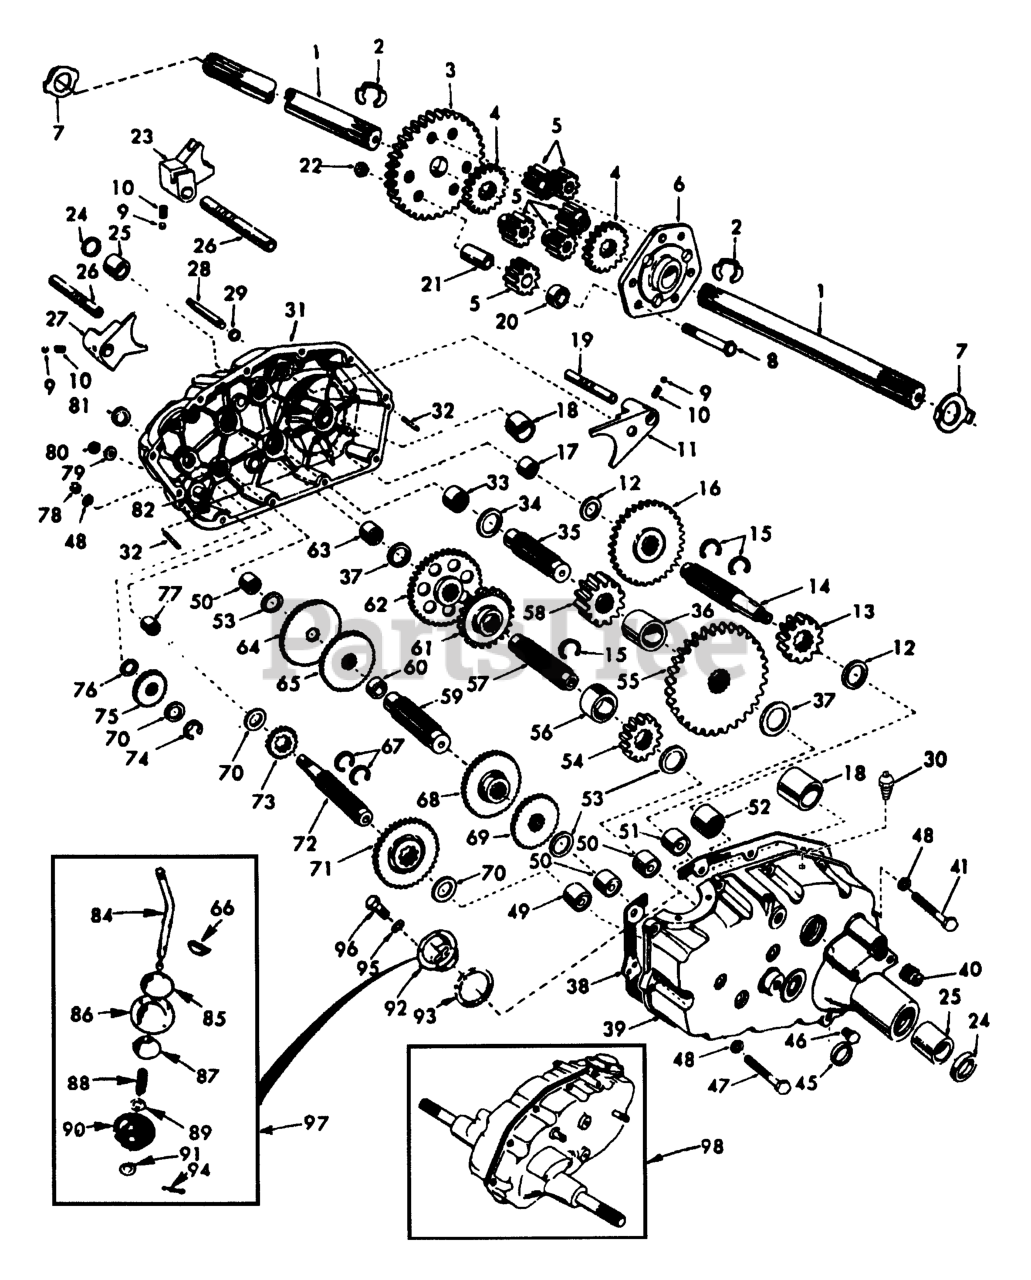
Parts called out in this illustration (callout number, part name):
1	AXLE SHAFT T
2	Retaining Ring
3	FINAL GEAR T
4	DIFF GEAR T
5	DIFF PINION T
6	DIFF CARRIER T
7	WASHER T
8	Bolt, Hex Head 3/8-24 x 3-1/4 (1" Thread Length)
9	STEEL BALL KIT
10	SPRING
12	THRUST WASHER
13	RED PINION T
14	GEAR SHAFT T
15	SNAP RING T
16	GEAR T
18	BEARING
21	PINION RS
22	GRIPCO NUT
24	OIL SEAL STD
25	BRNG. T
26	SHAFT T
27	SHIFT FORK T
28	SHIFT SHAFT
29	SEAL.OIL.SHAFT.SHIFT.T
31	TRANSAXLE 6SP GT
33	NEEDLE BRNG T
34	WASHER RACE BEARING THRUST
35	GEAR SHAFT T
36	GEAR SPACER T
39	Gearcase and Bearings, L.H.
40	Pipe Plug 1/2-14 N.P.T.
41	Bolt, Hex 5/16-18 UNC x 1-5/8
47	HEX BOLT
48	WASHER.LOCK.HVY.HLCL.SPR.5/16
49	BEARING TI
50	NEEDLE BRNG T
51	NEEDLE BRNG T
52	BEARING STD
53	BRNG RACE T
54	RED PINION T
55	RED GEAR T
56	PINION SPACER T
57	GEAR SHAFT T
58	FINAL PINION T
59	GEAR SHAFT T
61	RED PINION T
62	RED GEAR T
64	LOW SPEED GEAR T
65	GEAR.REVERSE.T
67	RING STD (1 2)
68	GEAR.SPEED.INTERMEDIATE.T/A
69	HIGH SPEED GEAR T
70	THRUST WASHER
71	CLUSTER GEAR T
72	INPUT SHAFT T
73	LO SPEED PINION T
74	RETAINING RING LT
75	IDLER GEAR T
77	NEEDLE BEARING TI
78	NUT
80	NUT **
81	SEAL STD
82	SHAFT T
84	GEAR SHIFT LVR T
86	COVER AND PIN T
87	GUIDE BALL T
89	WASHER
90	SEAL.SHIFT
91	Washer 9/16 x 15/16 x 12 Gauge
92	GEAR SHIFT GATE T
94	COTTER PIN
95	WASHER.LOCK.HVY.HLCL.SPR.5/16
96	BOLT
97	GEAR SHFT LVR T
98	TRANSAXLE 6SP.GT
